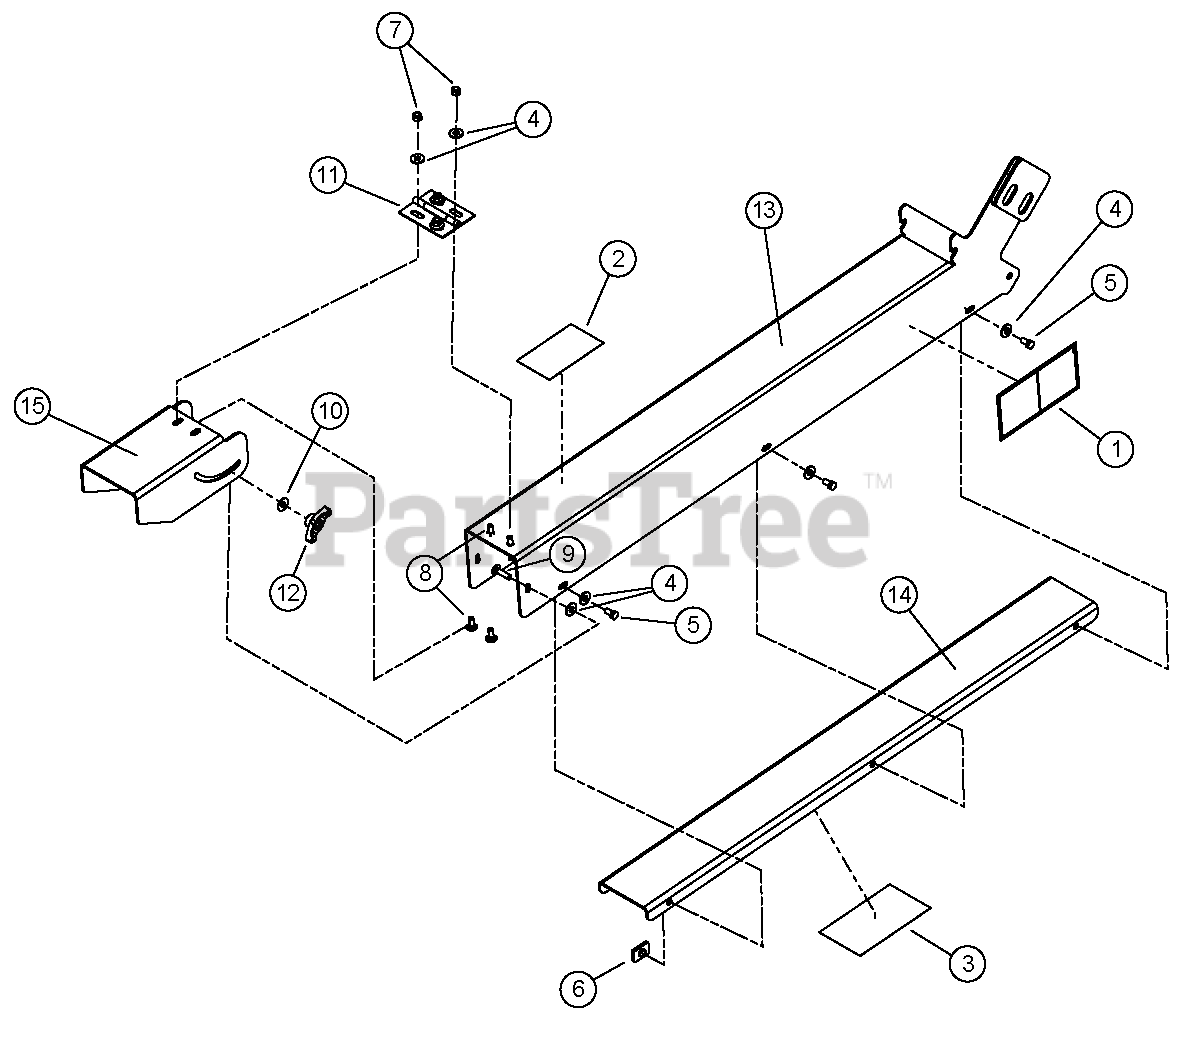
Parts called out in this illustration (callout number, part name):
1	DECAL, KNIFE ACCESS
2	DECAL, DISCHARGE
3	DECAL, INLET AND DISCHARGE
4	WASHER, 5/16" FLAT ZP
5	BOLT, 5/16 X 5/8" HHCS GR5 ZP
6	WASHER, 5/16" ID, 7/8" OD NYLON FLAT
7	NUT, 5/16" NE NYLOCK ZP
8	BOLT, 5/16 X 3/4" CARRIAGE NC GR5 ZP
9	BOLT, 5/16 X 1-1/4" CARRIAGE GR5 ZP
10	WASHER, 5/16 NYLON
11	HINGE, DISCHARGE CAP
12	KNOB, 5/16-18 UNC TEE WITH LOCKING INSERT
13	WELDMENT, CHIPPER DISCHARGE
14	WELDMENT, TOP DISCHARGE CHUTE
15	CAP, DISCHARGE
